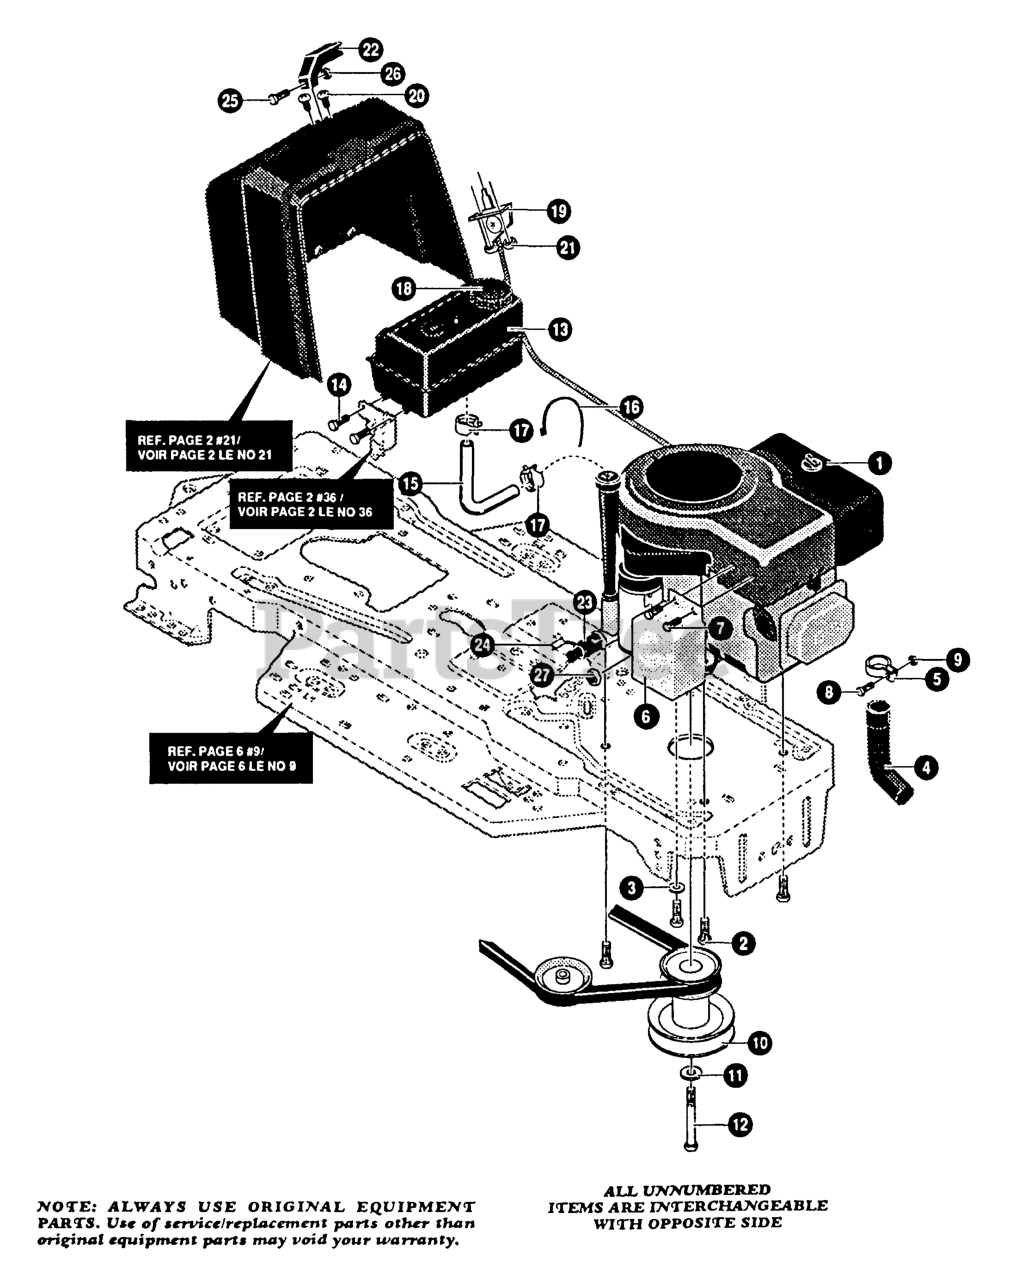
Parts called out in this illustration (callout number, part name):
1	ENGINE *
2	SCREW
4	EXHAUST TUBE
5	CLAMP EXHAUST
6	HEAT SHIELD
10	PULLEY, ENGINE
11	WASHER
13	TANK, FUEL
15	TUBING, GAS LINE
16	TIE, CABLE
17	CLAMP, HOSE
18	CAP, FUEL
19	THROTTLE
22	KNOB, THROTTLE
23	OIL DRAIN ASSY
24	CAP, OIL DRAIN
